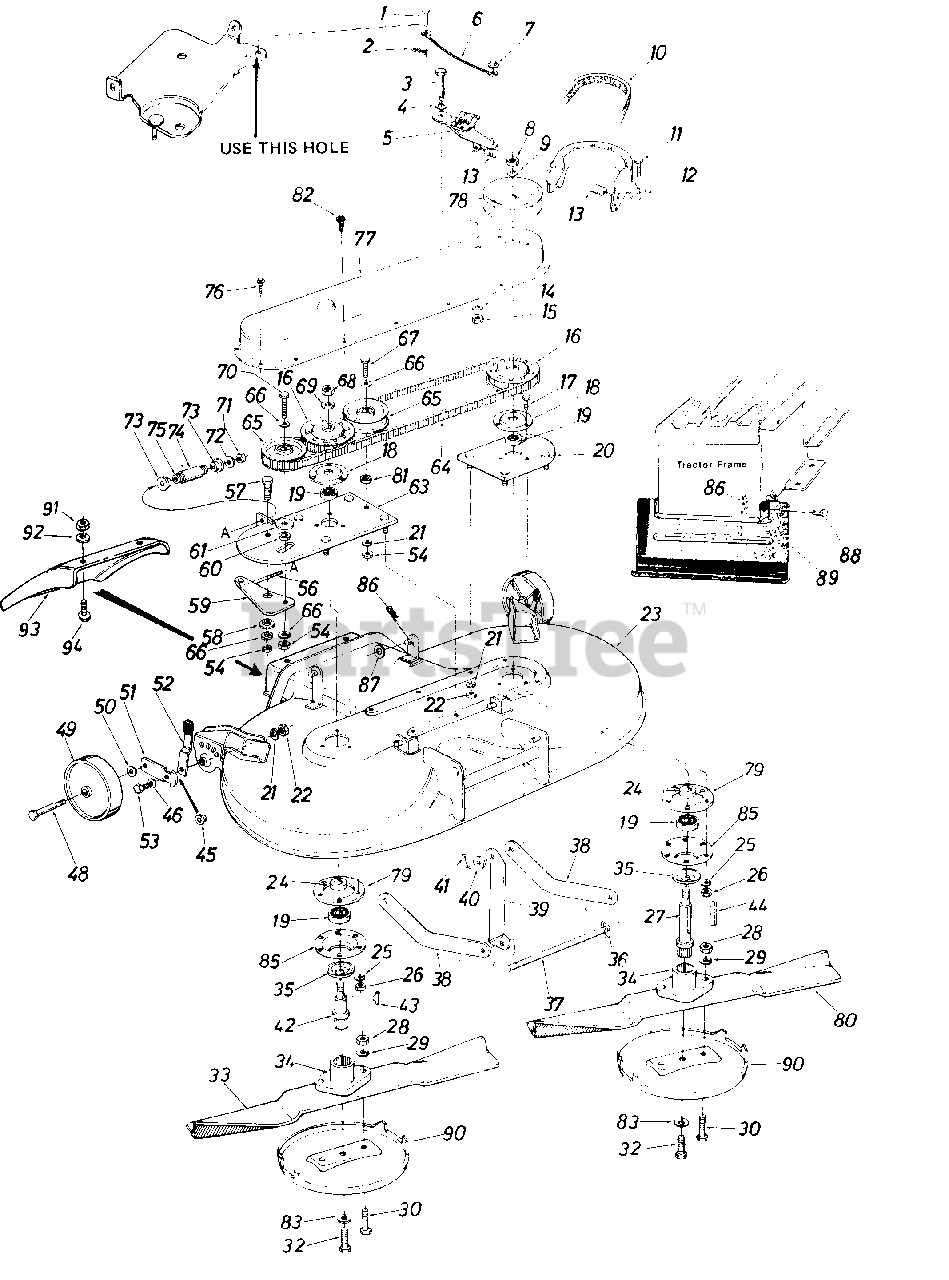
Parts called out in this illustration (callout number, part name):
1	Clevis Pin 1/4" Dia. x 1/2" Lg.
2	Hairpin Cotter 1/4" Dia.
3	Shld. Bolt .437" Dia. x.150" Lg. (5/16-18)
4	Wave Washer 7/16" Scr.
5	Spindle Brake Arm Ass'y.
6	Brake Cable Ass'y.
7	Push Cap 1/4" Stud.
8	Hex Jam Nut 5/8-18 Thd.
9	Bell.-Wash. 5/8" I.D. x 1.25" O.D.
10	"V"-Belt 1/2" x 56" Lg.
11	Hex Wash Hd. Self Tap Scr. 1/420 x .50"Lg
12	Belt Guard
13	Extension Spring
14	Bell.-Wash..340" I.D.
15	Hex Cent. L-Nut 5/16-18 Thd.
16	Sprocket Pulley Ass'y.
17	Hex Bolt 5/16-24 x 1.00" Lg. (Grade 5)
18	Bearing Housing
19	Ball Bearing.787" I.D. x 1.85" O.D.
20	Spindle Plate Ass'y.
21	L.-Wash. 3/8" I.D.*
22	HexJam Nut 3/8-2 Thd.
23	44" R.D. Deck Ass'y.
24	Spacer
25	L.-Wash. 5/16" I.D.*
26	Hex Nut 5/16-24 Thd.*
27	Blade Spindle - L.H.
28	Hex Nut 5/16-24 Thd.*
29	L.-Wash. 5/16" I.D."
30	Hex Bolt 5/16-24 x 1.00" Lg.
32	Hex Bolt Cent. L.-3/8 x 24 x .38 " Lq.
33	22.5" Blade-L.H. Rotation
34	Blade Adapter
35	Bearing Shield
36	Hairpin Cotter
37	Deck Connecting Rod
41	Cotter Pin 3/32" Dia. x 1.00" Lg.*
42	Blade Spindle - R.H.
43	Sq. Key 3/16" x 75" Lg.*
44	Sq. Key 3/16" x 1.50" Lg.*
45	Shoulder Spacer
46	Bell.-Wash. .400" I.D.
48	Shld. Bolt 3/8-16 x 1.41" Lg.
49	Wheel Ass'y. Comp. 6" x 1.38
50	Bell-Wash. 3/8" I.D.
51	Wheel Pivot Bar
52	Spring Lever Ass'y. w/knob
53	Hex Bolt 3/8-24 x 1.25" Lg. Grade 5
54	Hex Cent. L-Nut 3/8-24 Thd.
56	Adjustment Link 5/16-18 x 4-9/16" Lg.
57	Hex Bolt 3/8-24 x 1.00"
58	Shld. Spacer .625" I.D.
59	Belt Idler Brkt.
60	Spacer.380" I.D. x .625" O.D. x .265
61	Fl.-Wash. .38" I.D. x 1.37" O.D. x .125
63	Spindle & Idler Mount Plate Ass'y.
64	HTD Twin Power Belt
65	Fl.-IdlerPulley 3.50" O.D.
66	Bell.-Wash..38" I.D.
67	Hex Bolt 3/8-24 x 1.75" Lg. (Grade 5)
68	Hex Jam Nut 5/8-18 Thd.*
69	Bell.-Wash. 5/8" I.D.
70	Hex Bolt 3/8-24 x 2.00" Lg.
71	Hex Insert L.-Nut 5/16-18 Thd.
72	Fl.-Wash. 344" I.D. x 1.125" O.D. x .125
73	Shld. Spacer .625" I.D.
74	Spacer-Adj. Bolt
75	Compression Spring
76	Hex Wash. Hd. Self Tap. Scr. 1/4-20x.50" Lg.
77	Belt Cover
78	Deck Drive Pulley
79	Deck Reinforcement Plate
80	22.5" Blade-R.H. Rotation
81	Fl.-Wash. .38" I.D. x 1.00"O.D.
82	Hex Wash. Hd. Self Tap-Scr. 1/4-20 x . 75" Lg.
83	L.-Wash. 3/8" I.D. Heavy Duty
86	Hairpin Cotter
87	Fl.-Wash. 1/2" I.D.
88	Clevis Pin
89	Safety Shield -16 5/8" Lg.
90	Anti Scalp Plate
91	Hex Nut 1/4-20 Thd .*
92	L.-Wash. 1/4" I.D.*
93	Chute Deflector
94	Truss Mach. Scr. 1/4-20 x 50 " Lg
